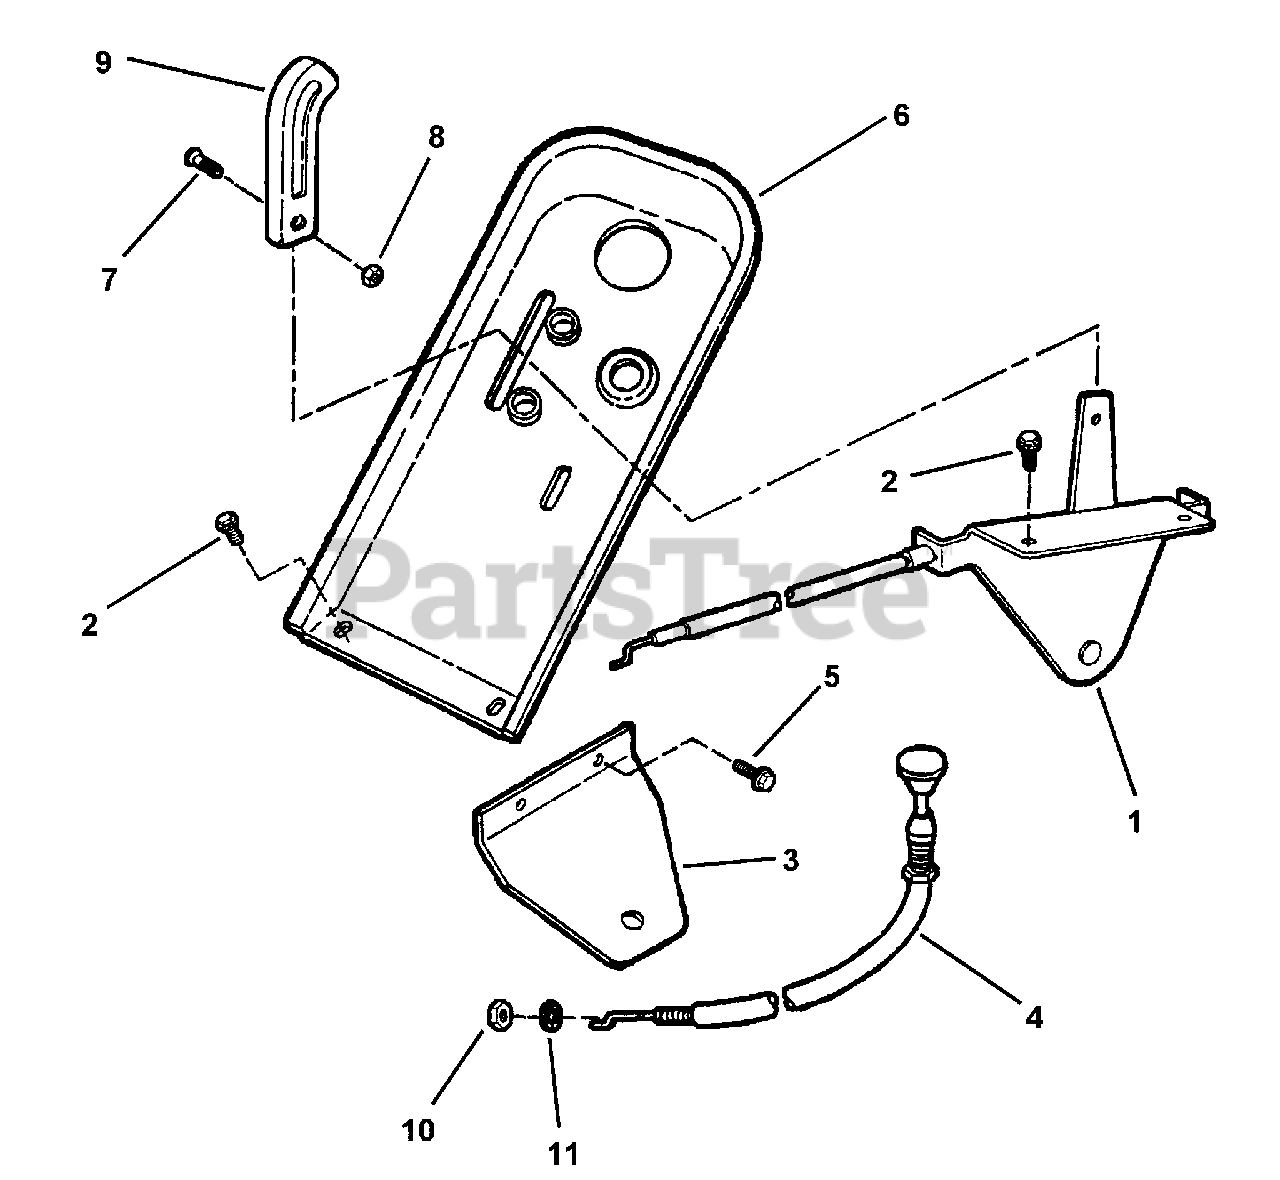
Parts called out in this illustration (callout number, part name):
1	CONTROL, Throttle (44.6" Long)
2	SCREW, #10-24 x 1/2" Hex Washer Self-Tap (Torx)
3	PLATE, Throttle Control
4	CONTROL, Choke (36" Long)
5	SCREW, 1/4-20 x 5/8" Self-Tap
6	COVER, Dash Panel
7	SCREW, #8-32 x 3/8" Cross-Recess, Fillister Head
8	NUT, #8-32 Hex
9	KNOB, Throttle Control
10	NUT, 3/8-24 Hex
11	WASHER, 3/8" Internal Tooth Lock
